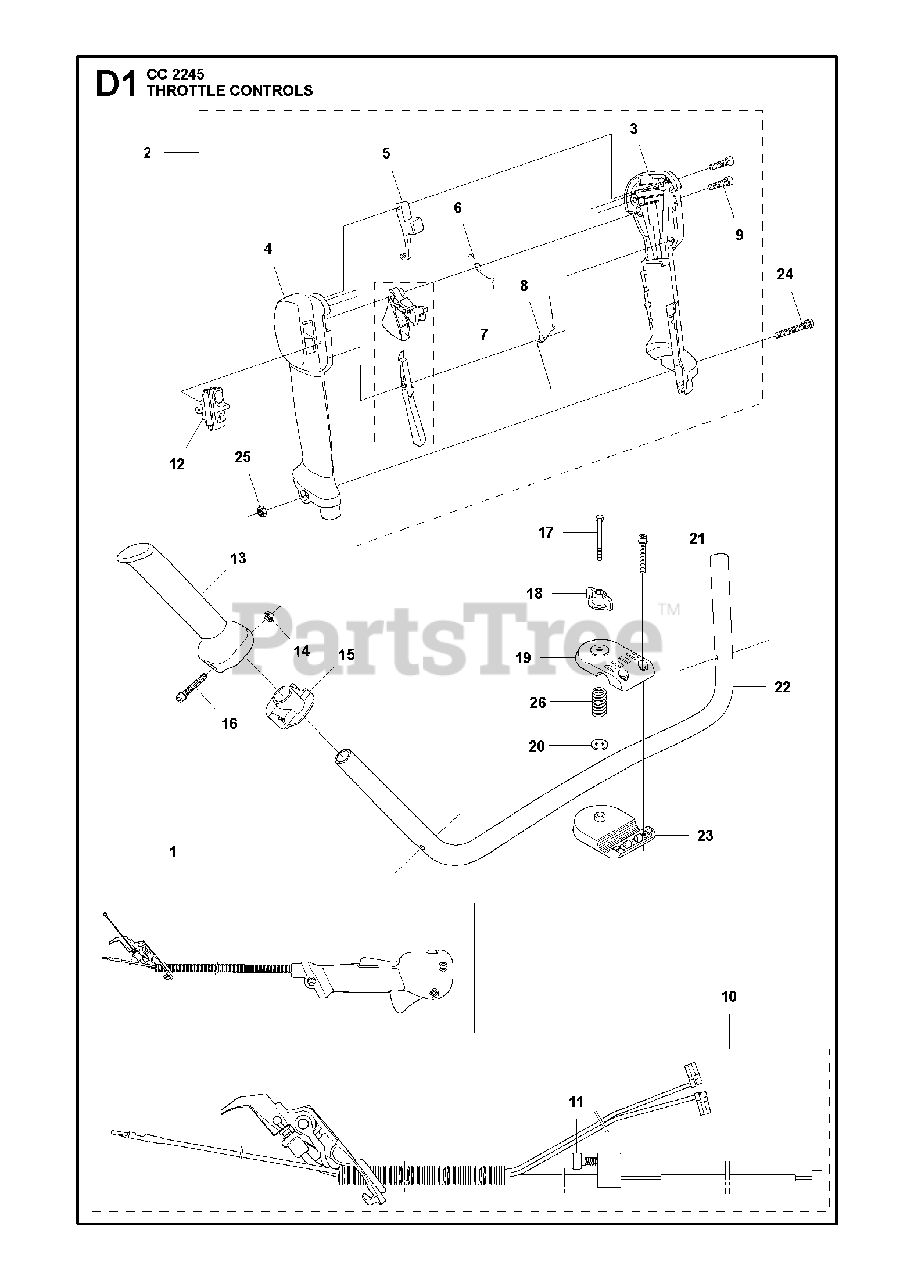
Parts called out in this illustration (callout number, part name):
2	THROTTLE HANDLE ASSY
3	HANDLE HALF RIGHT
5	SWITCH
6	SPRING
7	THROTTLE CONTROL
8	SPRING
9	SCREW
10	WIRING ASSY
11	SCREW
12	STOP BUTTON
14	NUT M6M M5
17	SCREW 6X70
19	HANDLE BRACKET
23	HANDLE BRACKET
24	%SCREW
